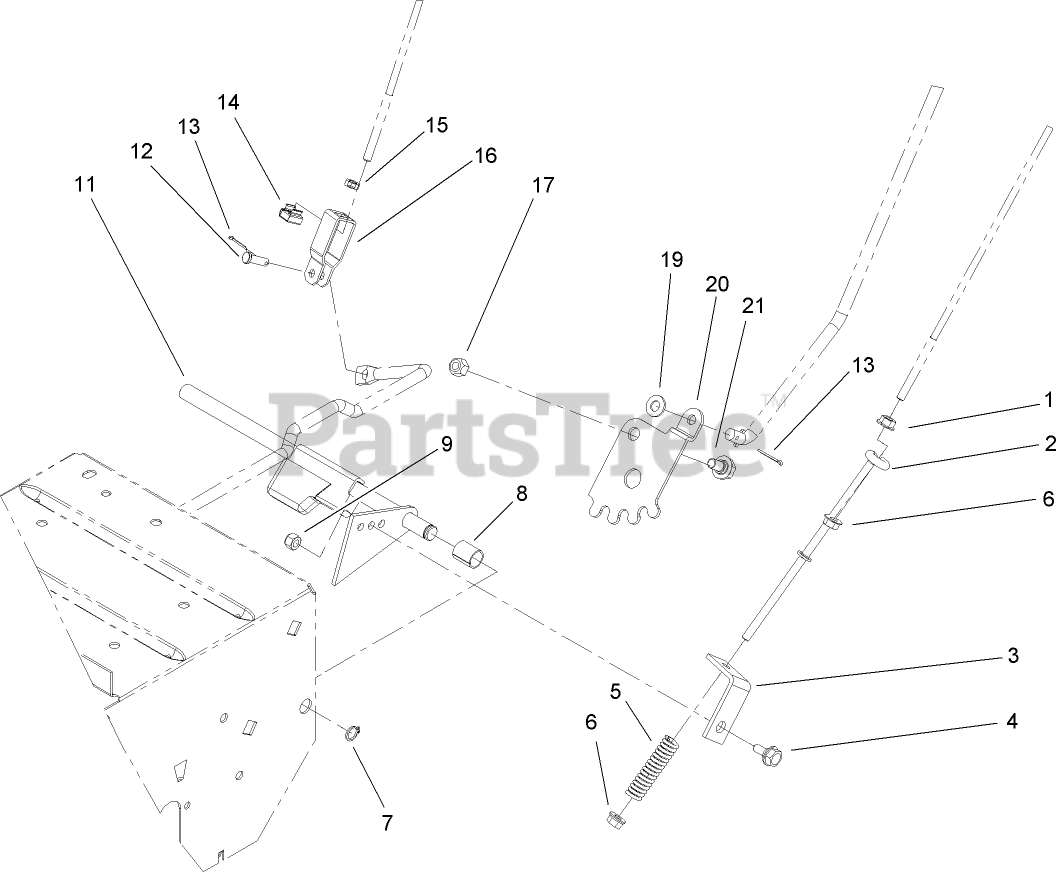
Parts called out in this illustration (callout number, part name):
1	NUT-HF
2	ROD-TRACTION, LOWER
3	BRACKET-TRACTION
4	SCREW
5	SPRING
6	NUT-HHF
7	RING-RETAINING
8	SPACER
9	NUT-LOCK, NI
11	TRACTION ARM ASM
12	PIN-CLEVIS
13	PIN-COTTER
14	NUT-RETAINED
15	NUT-JAM
16	CLEVIS
17	NUT-LOCK, NI
19	WASHER-PLAIN
20	GEAR-QUADRANT
21	BOLT-SHOULDER
